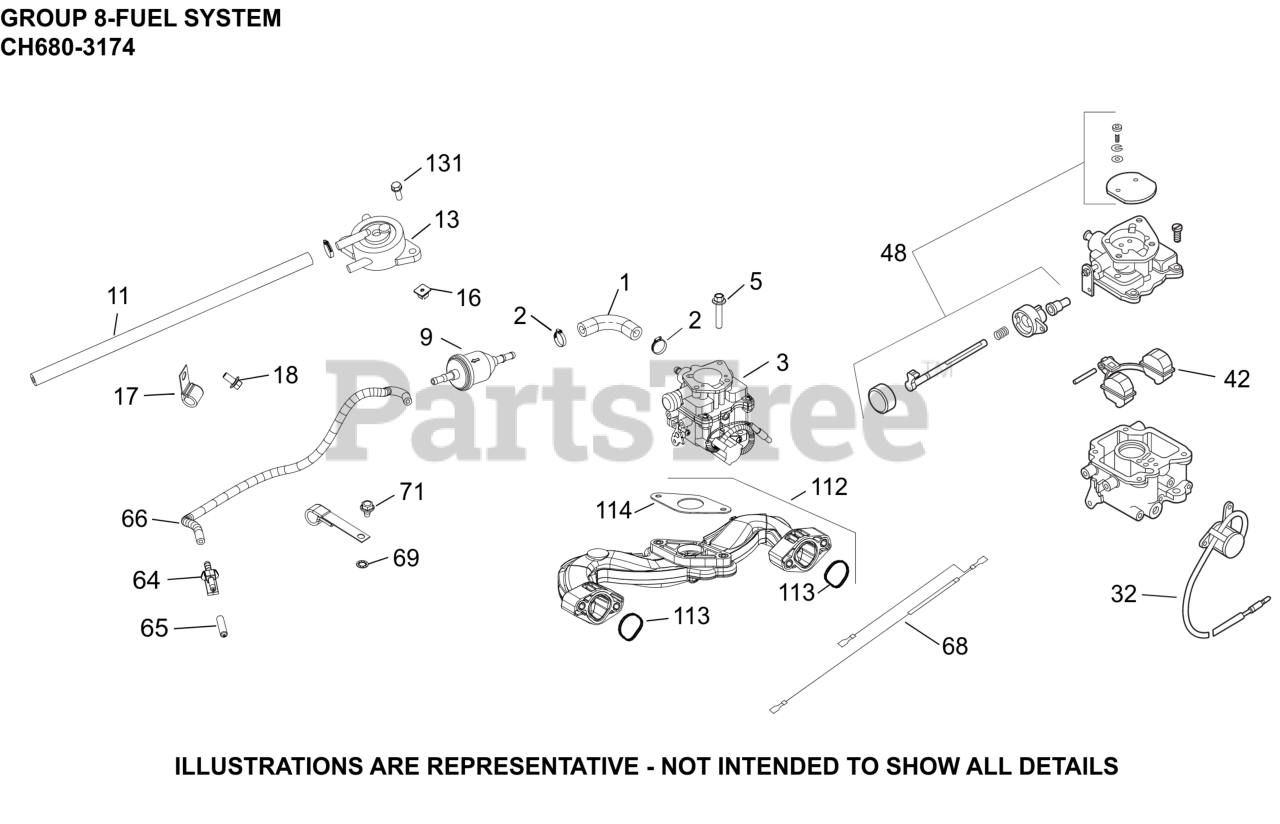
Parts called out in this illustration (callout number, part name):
1	HOSE, FUEL LOW PERMEATION 39"
1	HOSE,LW PERM.FUEL 24.00"-USE 25 111 81-S
2	CLAMP, HOSE (KM)-USE 25 237 31-S
3	KIT, CARBURETOR COMPLETE
5	SCREW, FLG M6X1.0X25
9	FILTER, FUEL
11	LINE, FLEXIBLE FUEL 15 1/2"
13	PUMP, FUEL
16	NUT, PLASTIC - BLACK
17	CLIP, CABLE (KM)
18	SCREW, FLG M6X1.0X12
32	KIT, SOLENOID
42	KIT, REPAIR FLOAT
48	KIT, REPAIR CHOKE
64	CONNECTOR, EVAPORATIVE
65	CAP, MASKING
66	HOSE, EVAPORATIVE 20"- (#24326143S)
68	LEAD, GROUND
69	WASHER, INT TOOTH LOCK 1/4"
71	SCREW, THREAD FORMING
112	INTAKE MANIFOLD W/GASKETS
113	O-RING, INTAKE PORT
114	GASKET, CARBURETOR (PIM, CH)
131	SCREW, HEX HEAD
NI	KIT, HIGH ALT (4000-8000 FT)
NI	KIT, HIGH ALT (8,000+ FT)
NI	KIT, REPAIR CARBURETOR
